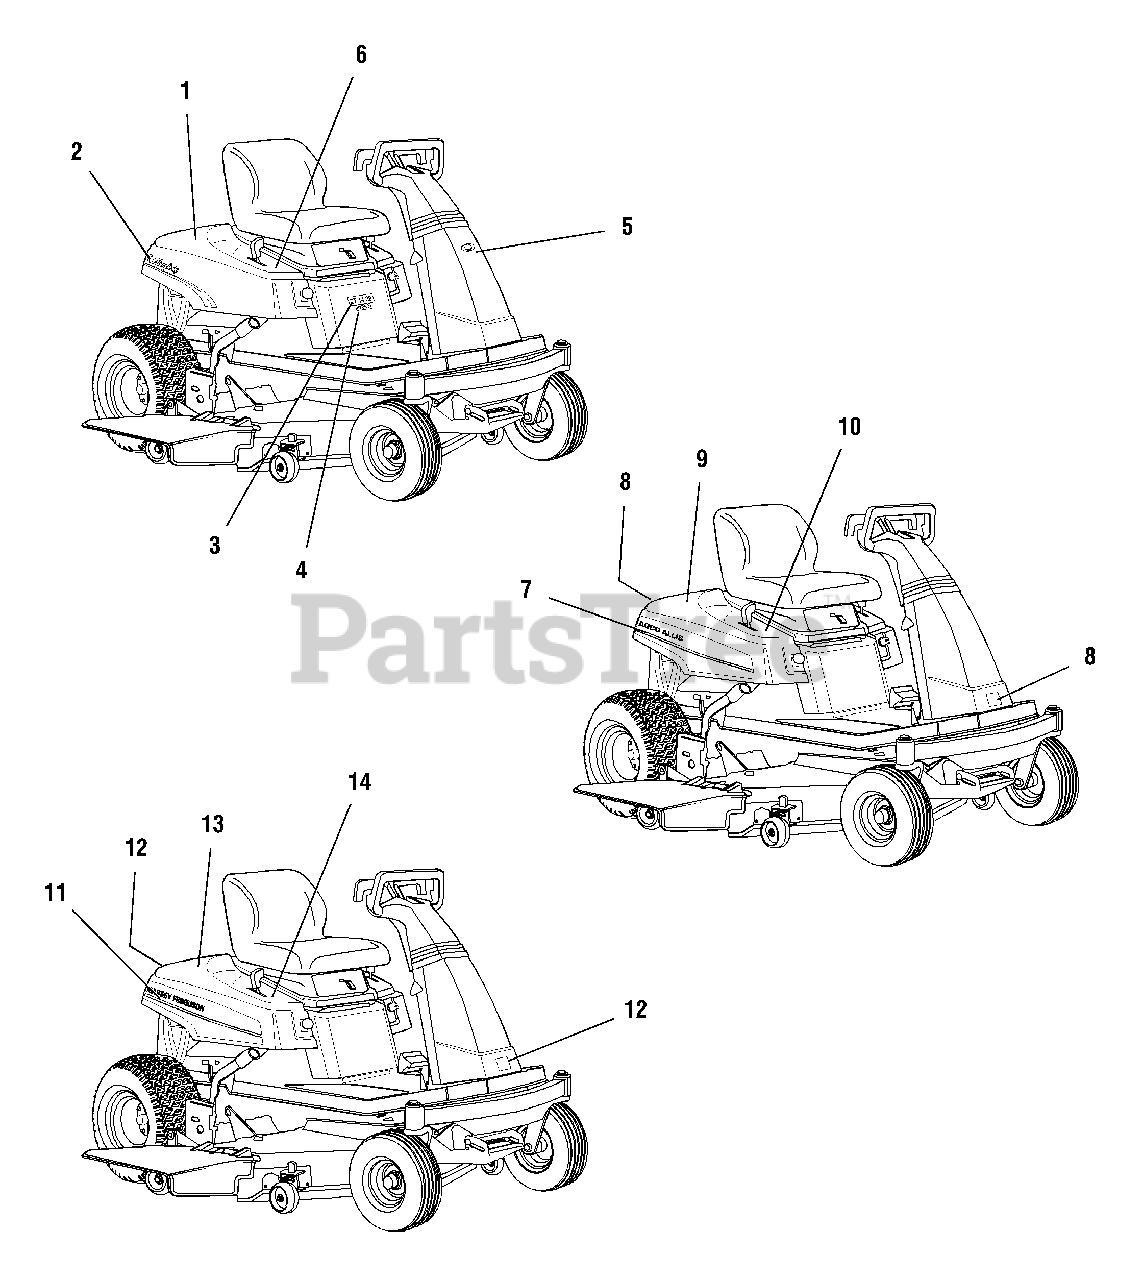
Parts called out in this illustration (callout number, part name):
1	DECAL, Touch-Up Paint, Simplicity (Under Seat Deck)
2	DECAL, Seat Deck, RH
2	DECAL, Seat Deck, LH
3	DECAL, "ZT 14 38"
3	DECAL, "ZT 16 44"
4	DECAL, "Hydro"
5	ICON, Simplicity
6	DECAL, Throttle & Choke
7	DECAL, Seat Deck LH
7	DECAL, Seat Deck RH
8	DECAL, Logo, AGCO Allis
9	DECAL, Touch-Up Paint, AGCO Allis
10	DECAL, Throttle & Choke
11	DECAL, Seat Deck LH
11	DECAL, Seat Deck RH
12	DECAL, Logo, Massey Ferguson
13	DECAL, Touch-Up Paint, Massey Ferguson
14	DECAL, Throttle & Choke
